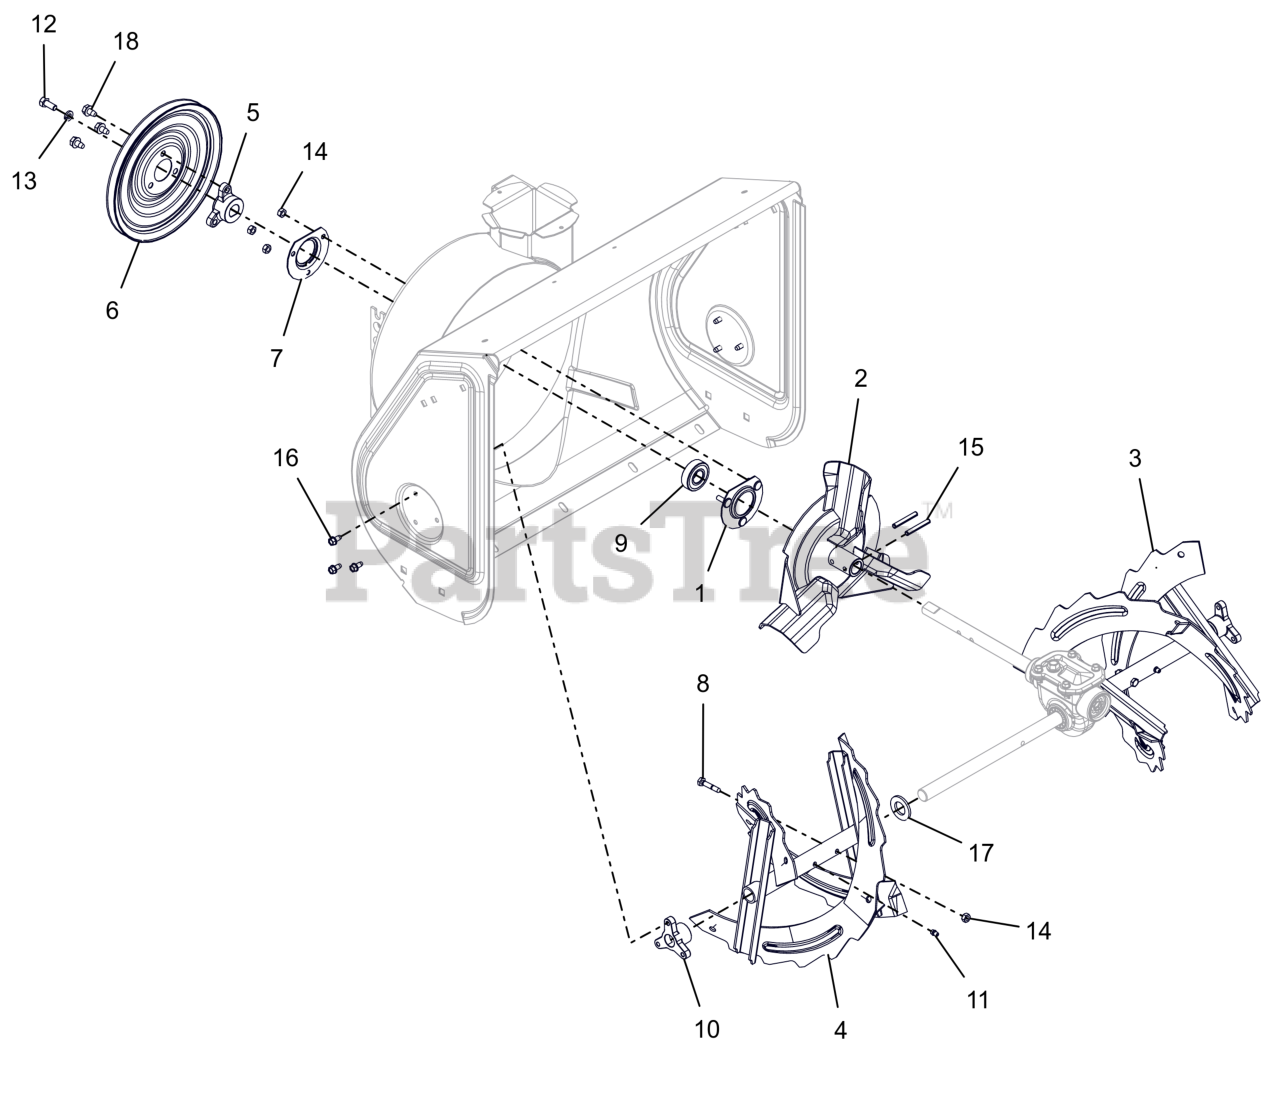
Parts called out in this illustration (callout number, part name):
1	BEARING FLANGE
2	IMPELLER, COMPACT 12" 3-BLADE
3	RAKE, 24" LH, BLK SERR W/ZERK
4	RAKE, 24" RH, BLK SERR W/ZERK
5	PULLEY HUB, BOLT-ON D-BORE .75
6	PULLEY,SPIN FORM SINGLE GROOVE
7	BEARING FLANGE
8	SHEAR BOLT WITH NUT
9	BRG-BALL .750X1.750X.50
10	BUSHING, RAKE SHAFT .75"
11	ZERK,FITTING .25X.125 DRIVE IN
12	BLT, HEX .31-24X.750 G5 ZCC
13	WSHR, LK-HVY .312X.097 ZCC
14	NUT,LK-CTR .25-20 GA ZCC
15	PIN-ROLL .250X1.75
16	SCR-TAP .25-20X.50 HWH ZCC
17	WSHR, FLT .812X1.469X.134 ZCC
18	SCR,TAP .312-18X.50 HWH TR ZCC
